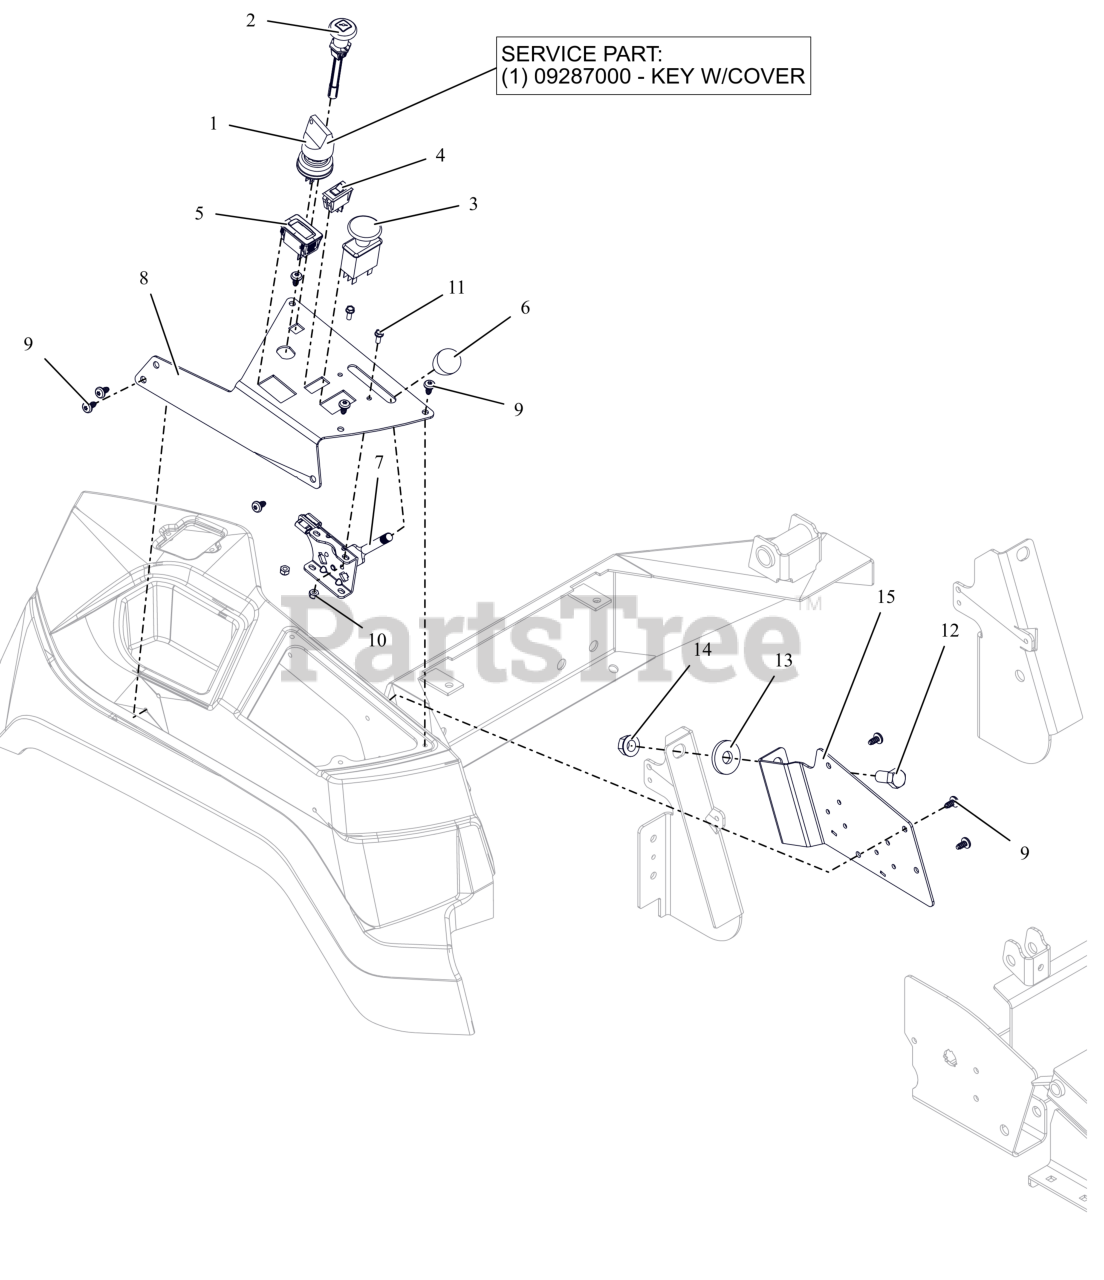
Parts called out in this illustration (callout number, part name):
1	SWITCH, IGNITION
1	KEY, W/ SHIELD
2	CABLE - CHOKE, SNAP-IN
3	SWITCH, CLUTCH
4	SWITCH, 2 POLE/ROCKER
5	HOUR METER
6	KNOB-CONTROL-BLACK .38-16X.50
7	CABLE, PRO THROTTLE CONTROL
8	PLATE, APEX CONTROL PANEL
9	SCR-PAN .25-15X.50 6L H/LZB500
10	NUT-LK-NYL #10-24 G2 ZCC
11	BLT, HWH #10-24X.50 ZCC
12	BLT, HEX .50-13X1.00 G5 ZCC
13	WSHR-FL-STL 0.562X1.5X0.187 ZCC
14	NUT-LK-CTR-FLG .500-13 GG ZCC
15	BRKT, FENDER/RELAY MOUNTING
